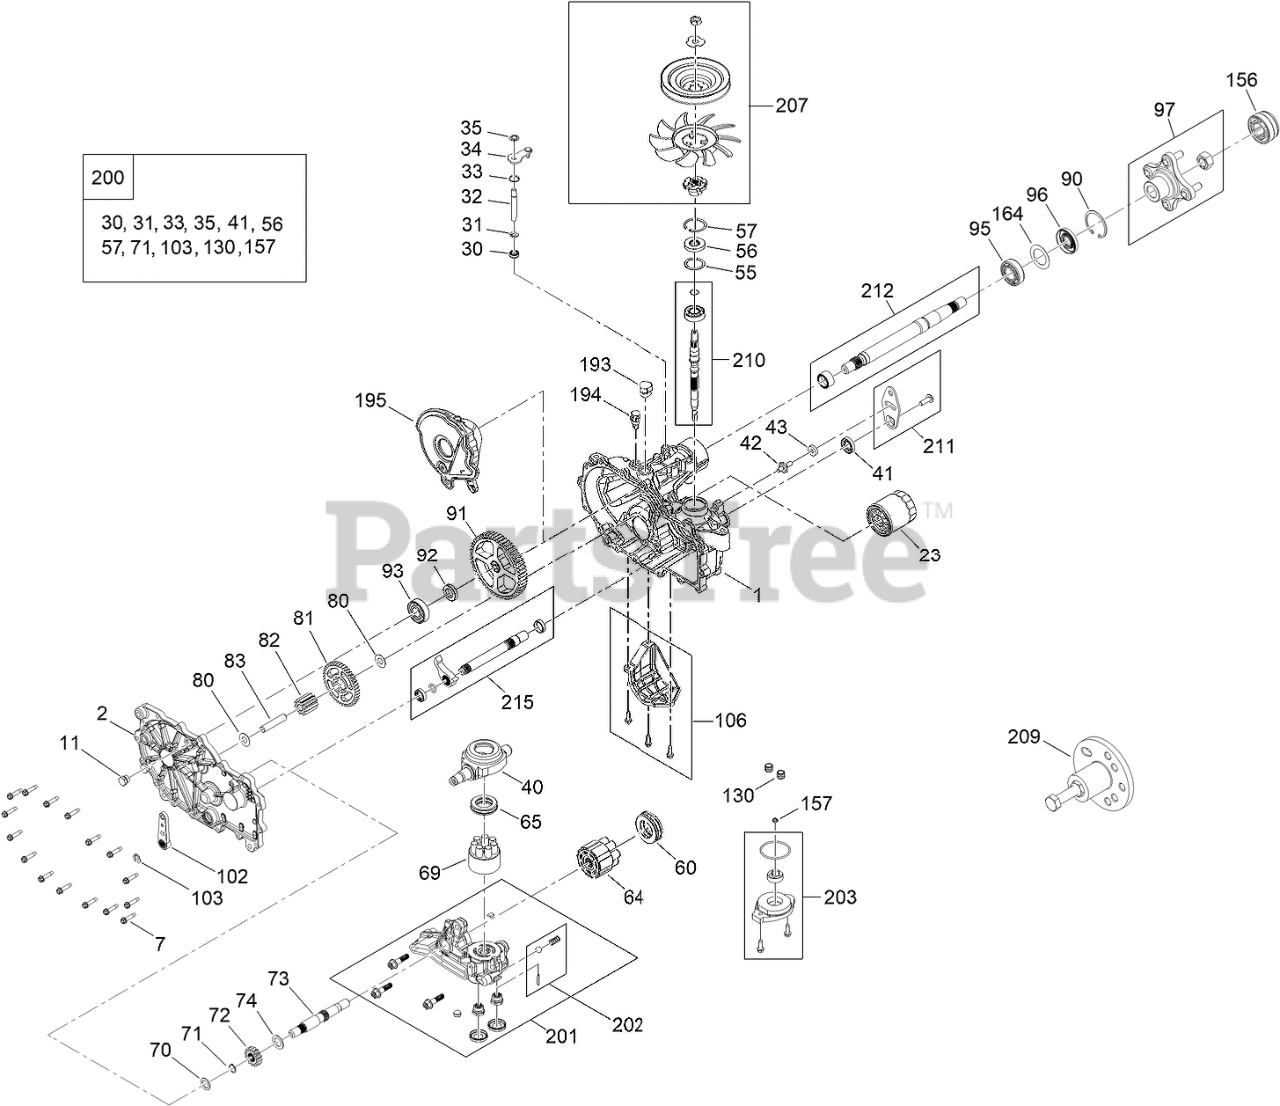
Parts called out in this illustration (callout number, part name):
1	LH MAIN HOUSING KIT
2	LH SIDE COVER KIT
7	SCREW-HHF
23	ELEMENT-OIL FILTER, HYD
30	SEAL-LIP
31	RING-RETAINING, EXTERNAL
32	ROD-BYPASS
33	RING-RETAINING, INTERNAL
34	ARM-BYPASS
35	RING-RETAINING, EXTERNAL
40	SWASHPLATE-TRUNNION
41	SEAL-LIP
43	PUCK-FRICTION
55	SPACER
56	SEAL-LIP
57	RING-RETAINING
60	BEARING-THRUST
64	CYLINDER BLOCK ASM KIT
65	BEARING-THRUST
69	PUMP BLOCK ASM
70	WASHER-FLAT
71	RING-RETAINING
72	GEAR-14T
73	SHAFT-MOTOR
74	WASHER
80	WASHER
81	GEAR-45T
82	GEAR-11T
83	PIN-JACKSHAFT
90	RING-RETAINING
91	GEAR-54T
92	SPACER
93	BEARING-BALL
95	BEARING-BALL
97	HUB KIT
102	HANDLE-BRAKE
103	RING-RETAINING, EXT
106	FILTER GUARD KIT
130	TUBE-CHARGE
156	COVER-NUT, AXLE
157	GEROTOR SEAL KIT
164	SPACER
194	BREATHER FITTING ASM
195	LH INTERNAL EXPANSION TANK ASM
200	SEAL KIT
201	KIT, CENTER SECTION, RH CHARGE
202	CHARGE RELIEF KIT
203	CHARGE KIT
207	FAN AND PULLEY KIT
210	INPUT SHAFT KIT
211	CONTROL ARM KIT
212	AXLE SHAFT KIT
215	INBOARD KIT
